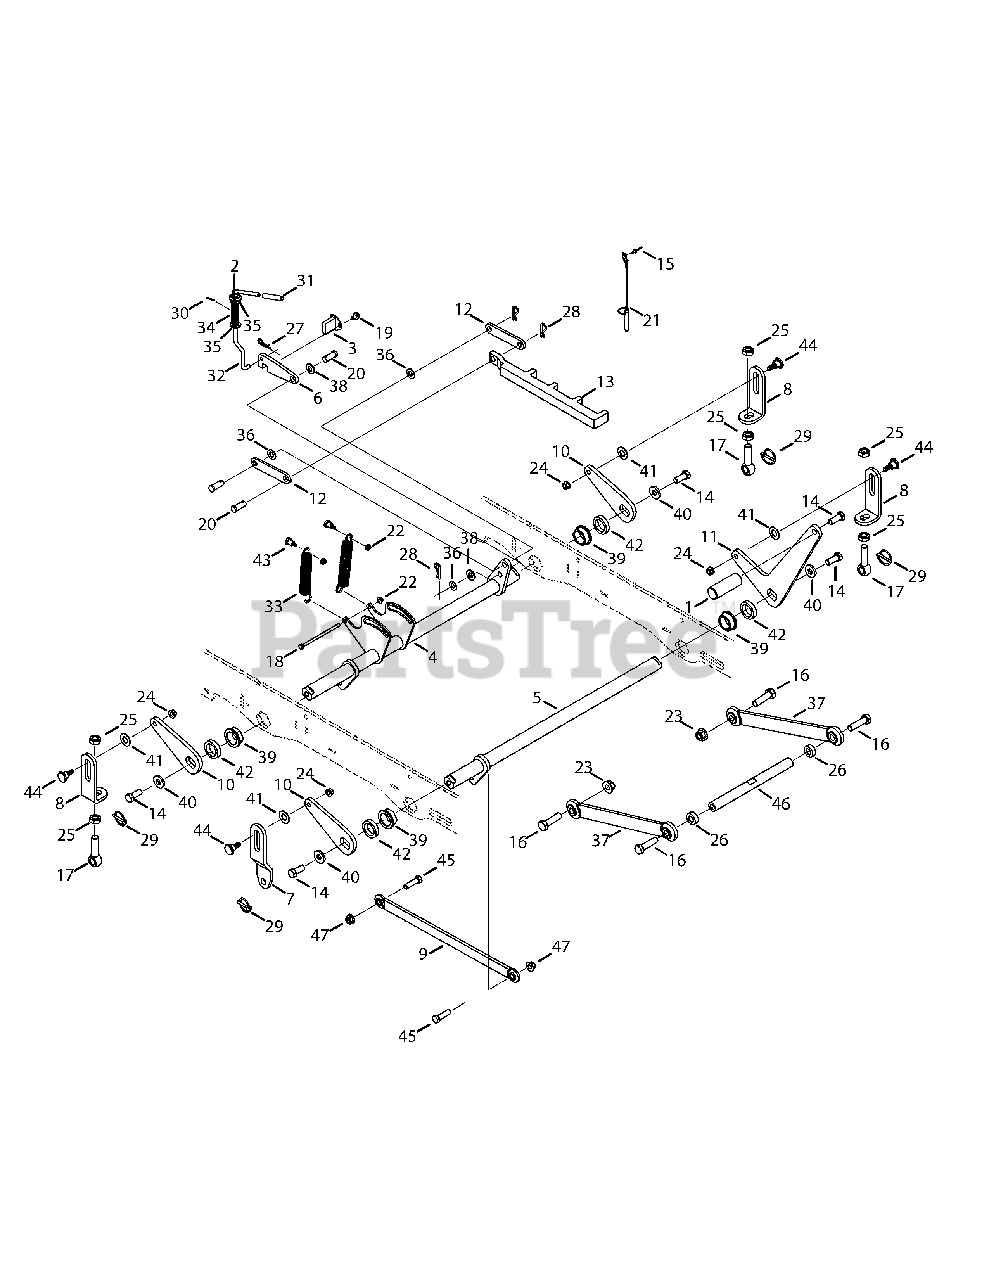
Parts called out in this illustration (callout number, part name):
1	Deck Lift Foot Pedal
2	Bearing, .385 ID
3	Lift Lock Mount
4	Deck Lift Shaft, Rear
5	Deck Lift Shaft, Front
6	Latch Lock Bracket
7	Lift Link Arm
8	Deck Adjustment Lift Link Arm
9	Deck Lift Arm Assembly
10	Deck Lift Bellcrank
11	Deck Lift Foot Pedal
12	Deck Index Link Arm
13	Lift Index Slider Arm
14	Hex Cap Screw, 1/2-13 x 1.25
15	Rivet, 3/16 x .325
16	Hex Cap Screw, 5/8-11 x 2.25
17	Eye Bolt, 5/8-18 x 2.63
18	Hex Cap Screw, 1/4-20 x 5.00
19	Screw, 5/16-18 x .500
20	Clevis Pin, .500 x 1.25
21	Clevis Pin, .438 x 1.5
22	Nut, 1/4-20, Flangelock
23	Nut, 5/8-11, Flangelock
24	Nut, 3/8-16, Flange Centerlock
25	Jam Nut, 5/8-11
26	Spacer, .635 x 1.25 x .445
27	Click Pin, .092 x 1.64
28	Internal Cotter Pin
29	Lynch Pin, .1875
30	Cotter Pin, 3/32 x .750
31	Lift Handle Grip
32	Lift Lock Rod
33	Extension Spring, .969 OD x 6.180
34	Compression Spring, .656 OD x 2.445
35	Bevel Washer, .340 x .872 x .060
36	Washer, .510 x 1.00 x .125
37	Deck Rod Assembly
38	Washer, .510 x 1.00 x .125
39	Hex Flange Bearing
40	Flat Washer, .531 x 2.125 x .250
41	Washer, .640 x 1.25 x .050
42	Spacer, 1.27 x 1.75 x .375
43	Shoulder Screw, .437 x .50, 1/4-20
44	Shoulder Screw, .625 x .442, 3/8-16
45	Hex Cap Screw, 1/2-13 x 1.75
46	Front Lift Link Shaft, Threaded
47	Nut, 1/2-13, Flangelock
